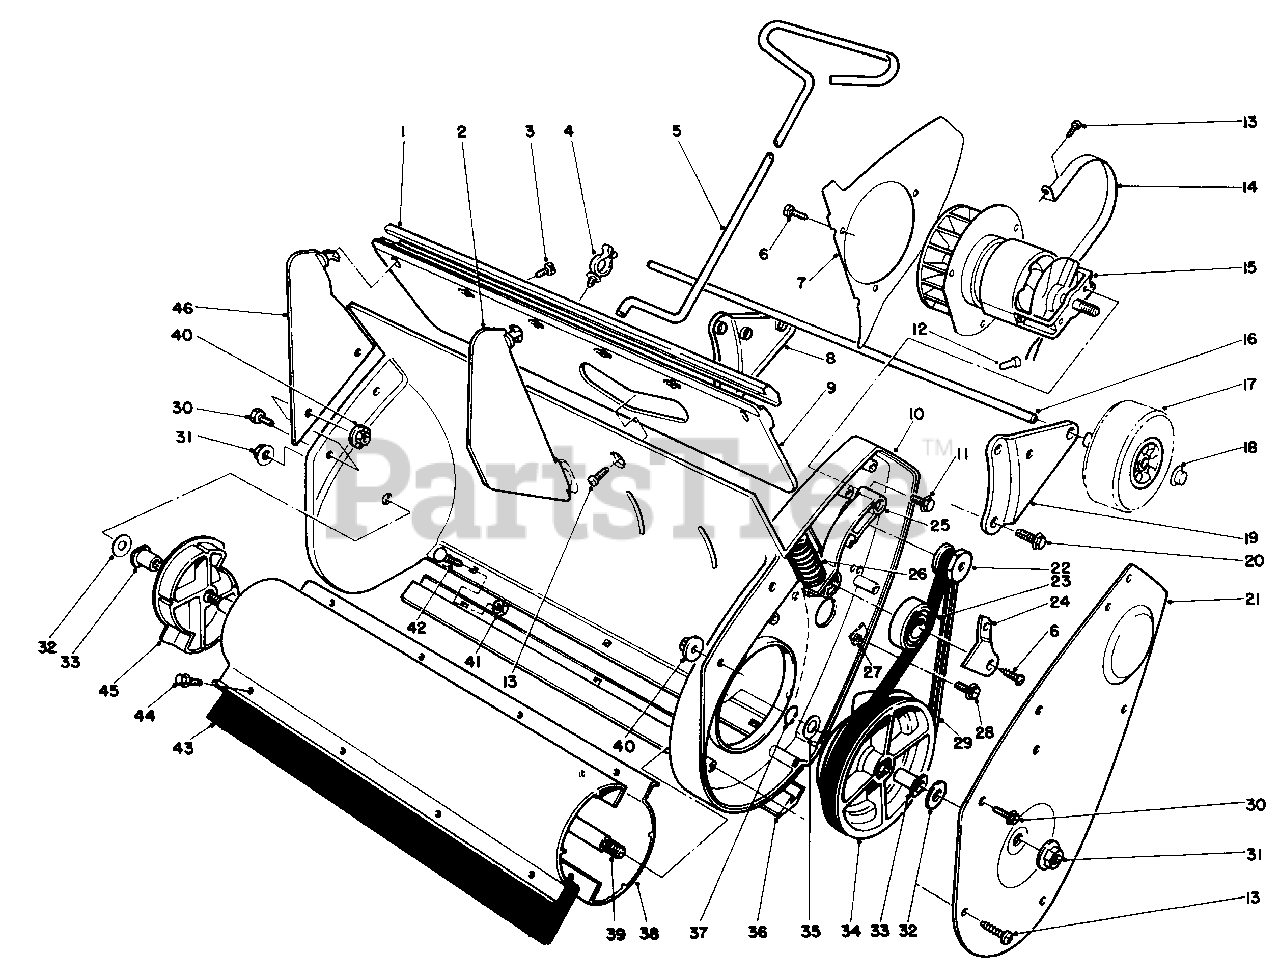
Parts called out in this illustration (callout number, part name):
1	Moulding
2	Vane-Inner
4	Wire Keeper
5	Rod-Vane Adjustment
6	Screw-Self Tapping Phillips Hd.
7	Air Baffle
8	Wheel Bracket R.H.
9	Vane Mount
11	Screw Hex Head Thread Forming
12	Wire Connector
13	Screw
14	Mount-Motor
16	Axle Shaft
18	Push Nut
19	Wheel Bracket L.H.
20	Screw
21	Cover-Belt Case
22	Drive Pulley
23	Ball Bearing
24	Retainer Idler Pulley
25	Idler Arm
26	Idler Spring
27	Tinnerman Nut
29	Drive Belt
30	Screw-Slotted Hex Washer Hd.
31	Nut-Flange
32	Thrust Washer
33	Rotor Bushing
34	Pulley-Driven
35	Thrust Washer
37	Retaining Ring
39	Shaft Rotor
42	Carriage Bolt
43	Blade-Rotor
44	Screw-Thread Forming
45	End Cap Rotor
46	Vane-Outer
